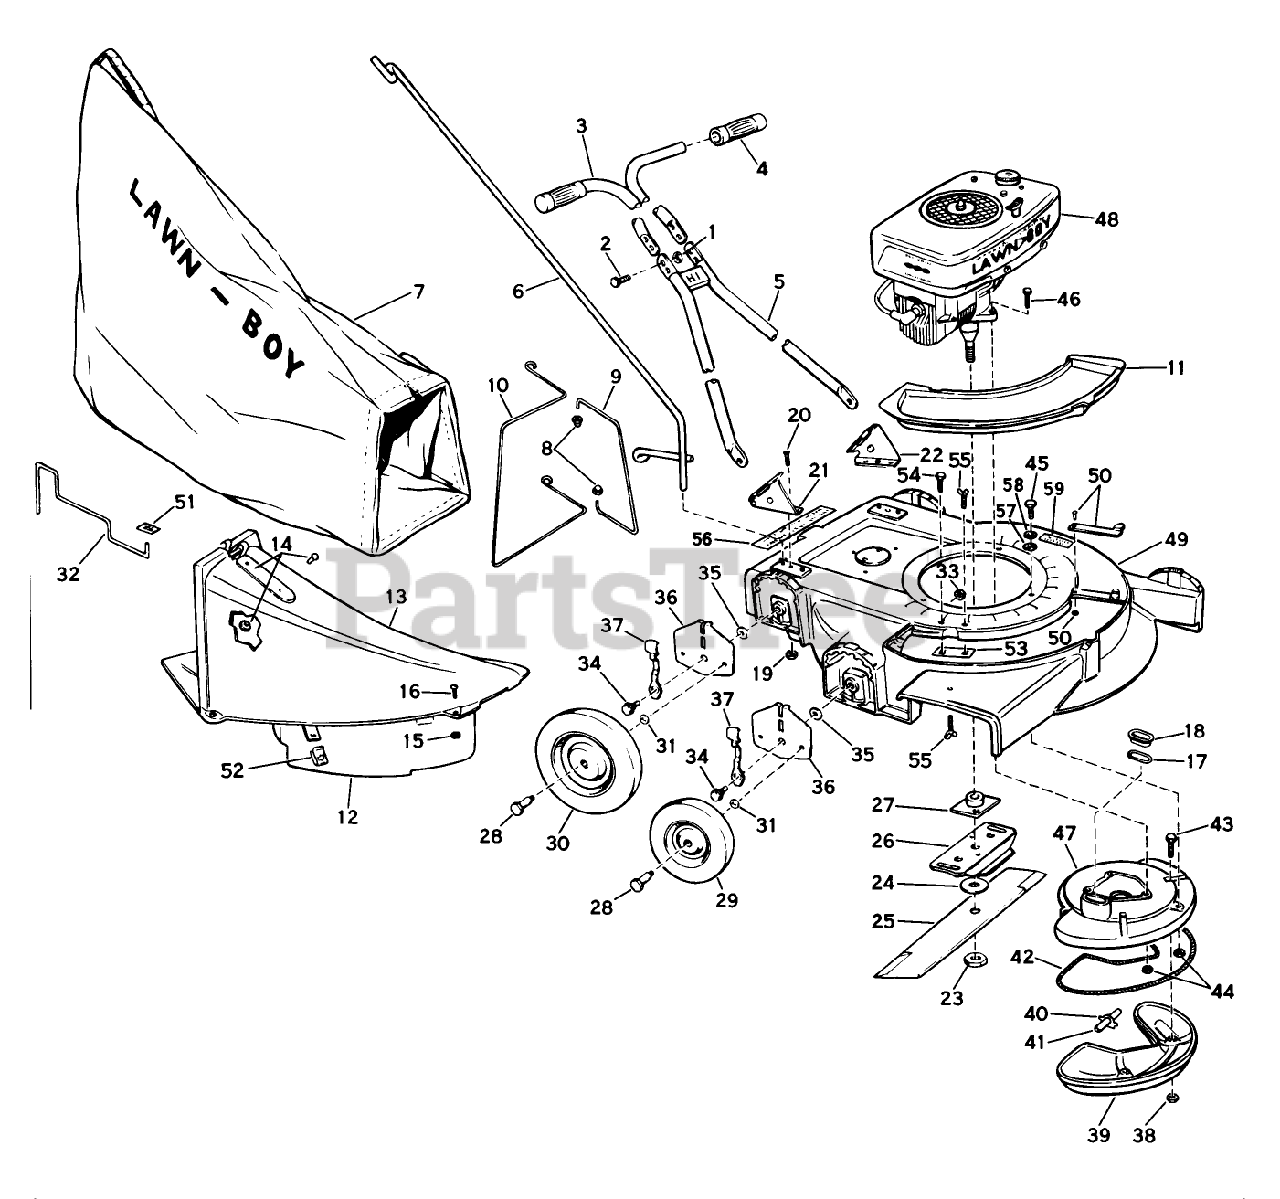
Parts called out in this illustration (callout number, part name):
1	STOP NUT
4	HANDLE GRIP
8	Nut-Self Threading
9	Frame, Left-Bag
12	Skirt Assembly-Chute (Includes Hardware)
13	Chute and Spring Assy. (Includes Hardware)
23	NUT-BLADE
27	PLATE AND COLLAR ASM
28	BOLT WHEEL
31	WASHER WROUGHT
38	LOCKNUT E
40	Gasket-Internal Tube
41	Tube-Internal Muffler
49	Housing Cover Assy. 21"
50	Spring, Rivet Washer Assy.
52	SPEED NUT ARDEN
56	Decal, Instruction
